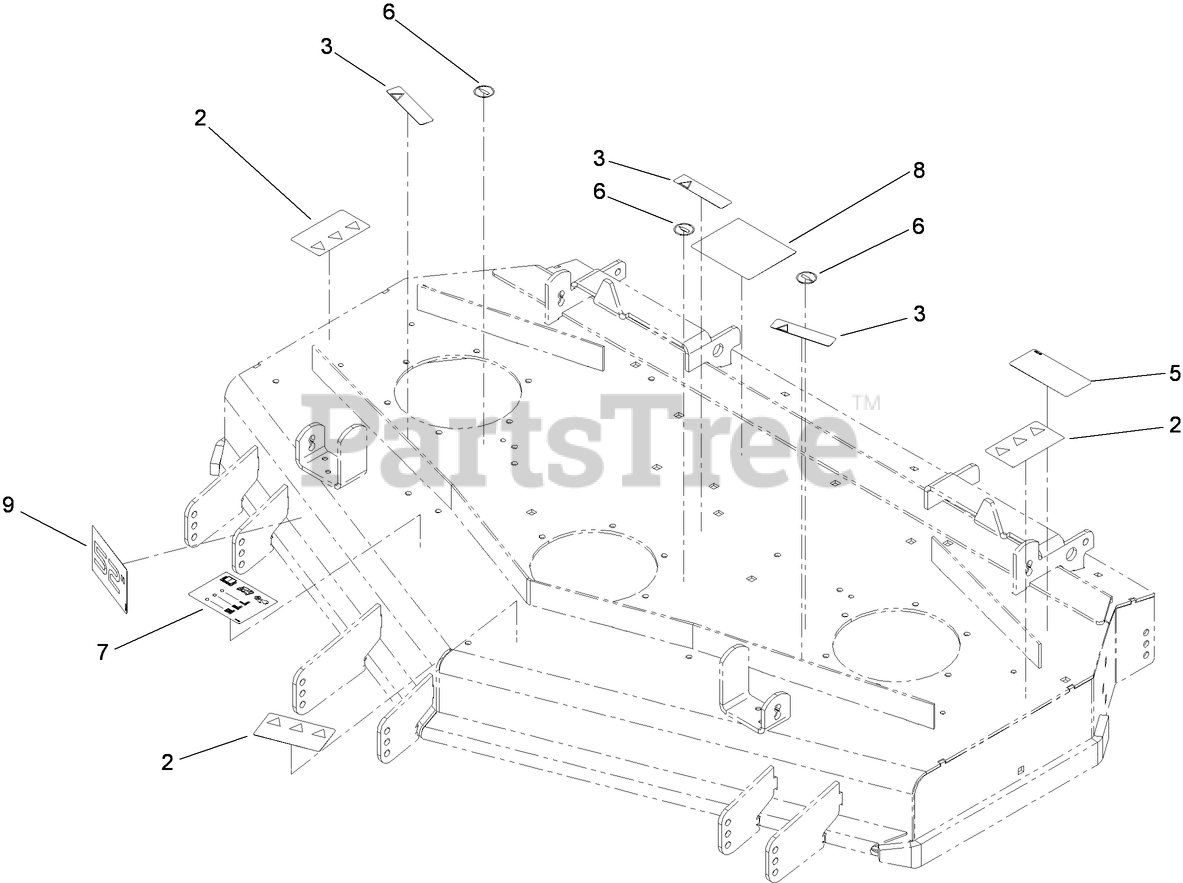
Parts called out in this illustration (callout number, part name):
2	DECAL-DANGER
3	DECAL-WARNING
5	DECAL-TORQUE, BLADE BOLT
6	DECAL-GREASE
7	DECAL-SCALP, ANTI
8	DECAL-ROUTING, BELT
